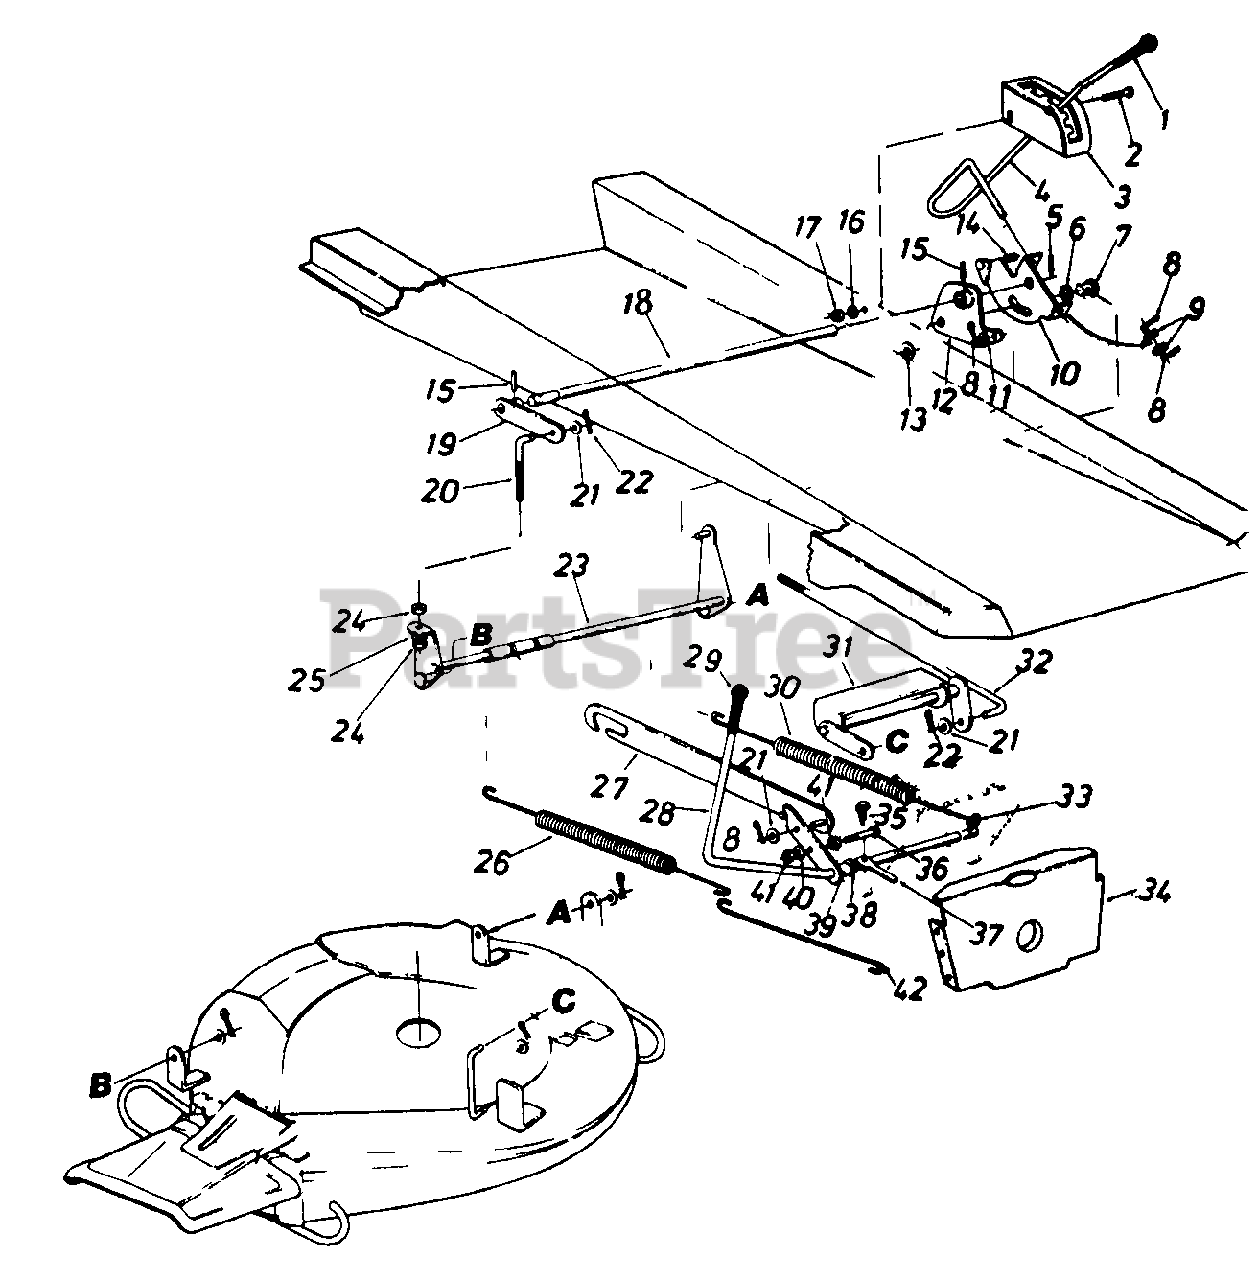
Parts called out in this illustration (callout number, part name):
2	Truss Mach. Scr. 5/16-18 x .75" Lg.
5	Spring Pin Spir 3/16" Dia. x 1.50" Lg.
6	Fl-Wash. .385" I.D. x .87" O.D.
7	Adj. Ferrule Deck Lift Handle
8	Sotter Pin 1/8" Dia. x 1.00" Lg.
9	Fl-Wash .531" I.D. x .930" O.D.
10	Deck Lift Handle Retainer Ass'y .
11	Fl-Wash. .385" I.D. x .87" O.D.
12	Deck Lift Brkt. Ass'y. L.H.
13	Fl-Wash. .635" I.D. x 1.04" O.D.
14	Compression Spring .50" Dia. x 1.0" Lg.
15	Spring Pin Spir. 114" Dia. x 1.50" Lg.
16	L-Wash. 5/16" I.D*
17	Hex Nut 5/16-18 Thd.
18	Rear Hgt. Adj. Shaft
19	Deck Lift Brkt. Ass'y. R.H.
20	Deck Adj. Scr. 3/8-16 Thd.
21	Fl-Wash. .385" I.D. x .87" O.D.
22	Intern. Cotter Pin 1/2" Dia.
23	Deck Link Ass'y. Rear
24	Hex Nut 3/8-16 Thd.
25	L-Wash. 3/8" I.D.
26	Extension Spring .73" O.D. x 13.84" Lg.
27	Deck Drive Control Bracket
28	Blade Engagement Lever Ass'y.
30	Extension Spring .73" O.D. x 13.89" Lg.
31	Deck Lift Ass'y. Front
32	Deck Lift Connecting Rod
33	Clevis Pin Special .250" Dia.
34	Pivot Bar Bracket
35	Hex TT-Tap Scr. 1/4-20 x .75" Lg.
36	Hex Bolt 5/16-18 x 1.50" Lg. (Grade 5)
37	Switch Actuator
38	Fl-Wash. .531" I.D. x .930" O.D.
39	Spacer .511" I.D. x .70" O.D. x.38" Lg.
40	L-Wash. 5/16" I.D.'
41	Hex Nut 5/16-18 Thd.
42	SPrinq Hook
